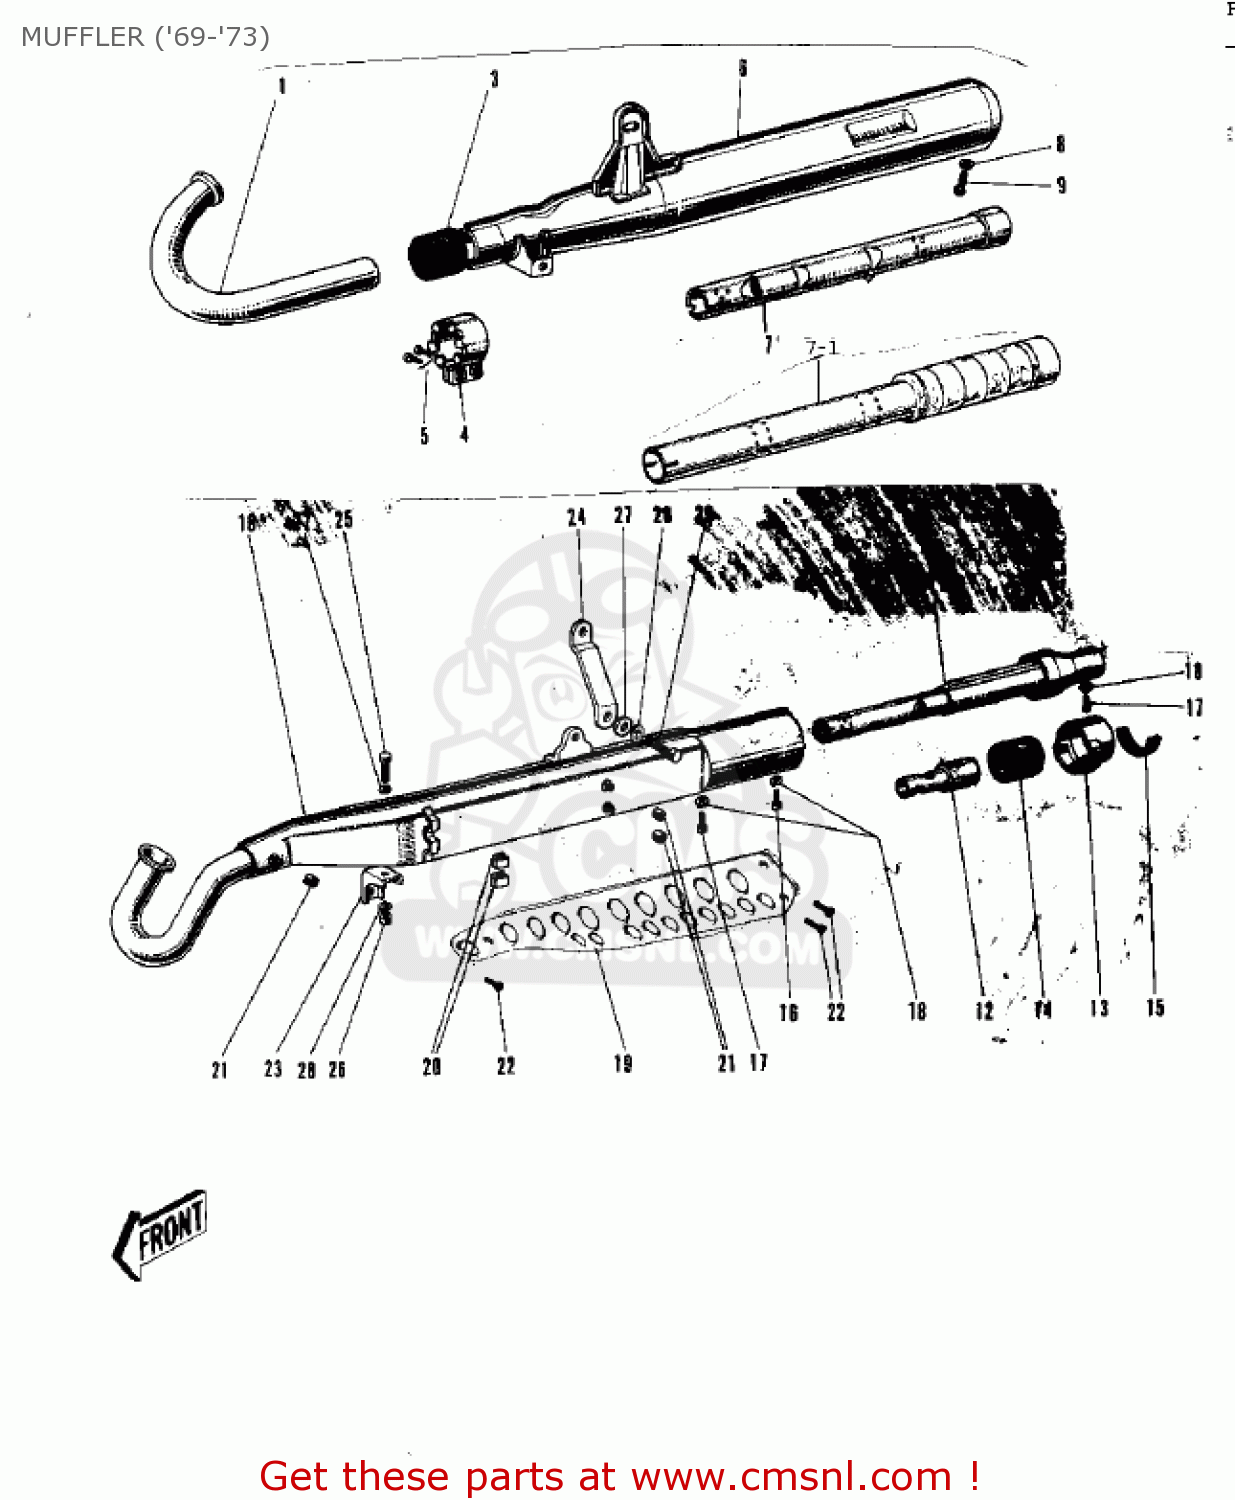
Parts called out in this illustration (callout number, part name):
1	PIPE-EXHAUST
3	SEAL,MUFFLER
4	HOLDER,MUFFLER CONECT
5	SCREW-PAN HEAD,6X25
7	BAFFLE TUBE
8	WASHER-SPRING,6MM
9	SCREW-PAN HEAD,6X8
10	MUFFLER ASSY
11	SPARK ARRESTER,COMPLETE
12	BAFFLE TUBE
13	TAIL PIECE
14	ELEMENT-TAIL PIECE
15	GASKET-TAIL PIECE (NAS)
17	BOLT,6X10
18	WASHER-LOCK,6MM
19	COVER-MUFFLER,BLACK
20	INSULATOR,HEAT
21	INSULATOR
22	SCREW-CNTSNK HD,6X10
23	BRACKET-FRONT MUFFLER
24	MUFFLER BRACKET,REAR
25	BOLT-HEX HEAD,8X16
26	NUT,8MM
27	WASHER-PLAIN-SMALL,8M
28	WASHER-SPRING,8MM
29	BOLT-HEX HEAD,8X16
?	BAFFLE TUBE
